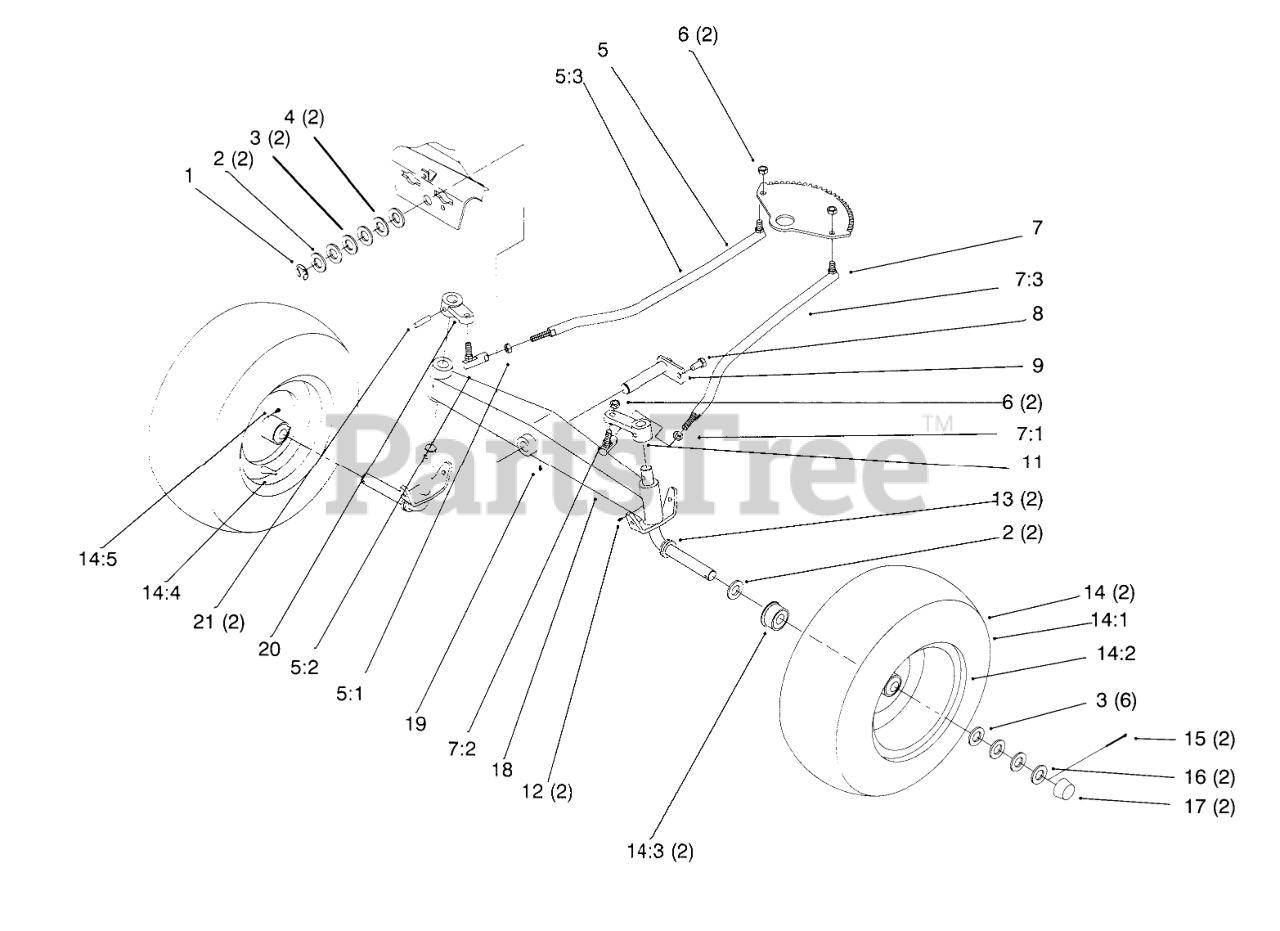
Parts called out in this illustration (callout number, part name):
1	E-RING
2	WASHER-SHIM
3	WASHER
4	Washer
5	LINKAGE-STEERING, RH
5:1	Nut-HJ
5:2	BALL-JOINT
5:3	Ball Link ASM
7	LINKAGE-STEERING, LH
7:1	Nut-HJ
7:2	BALL-JOINT
7:3	Ball Link ASM
8	SCREW-HWH, TAPTITE
9	PIN-AXLE
11	Arm-Front Spindle
12	FITTING-GREASE
13	SPINDLE
14	Wheel AND Tire ASM
14:1	Tire (16 x 6.5-8) 2-Ply -2 Wheel Axel
14:2	Wheel
14:3	BEARING-WHEEL
14:4	VALVE
14:5	ZERK-GREASE
15	PIN-COTTER
16	WASHER-PLAIN
17	CAP-HUB
18	AXLE-FRONT
19	FITTING-LUBE, 45 DEG
20	Arm-Front Spindle
